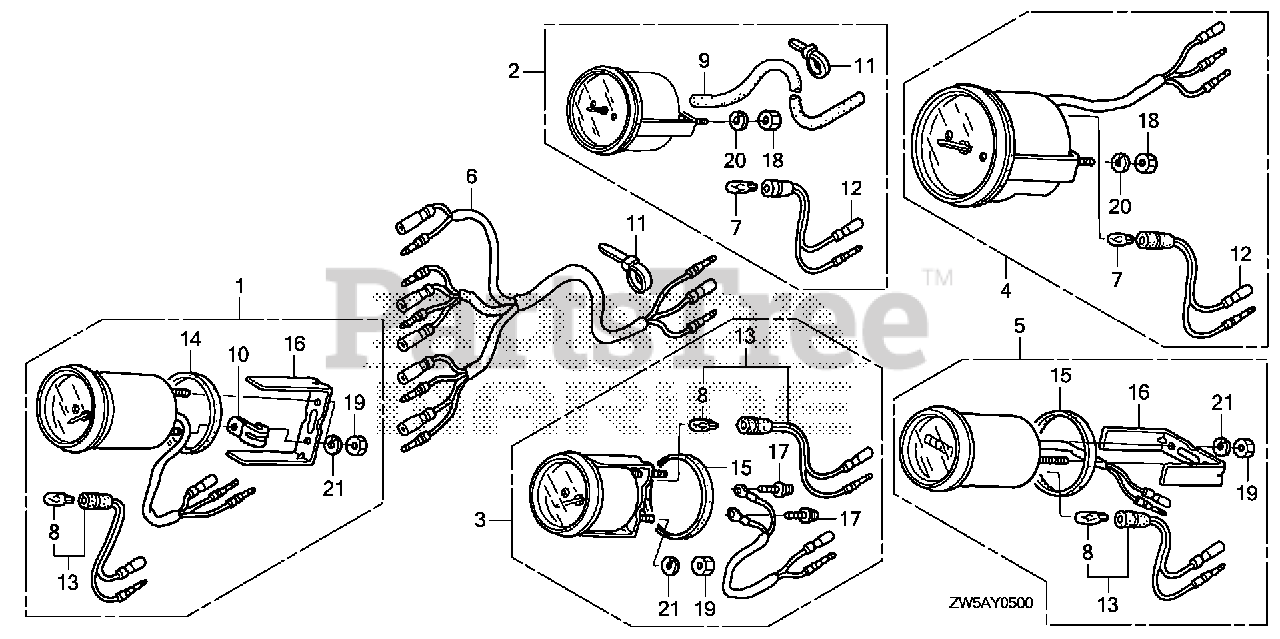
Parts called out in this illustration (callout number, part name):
1	METER KIT, TRIM (WHITE)
1	METER KIT, TRIM (B)
2	SPEEDOMETER KIT (WHITE)
2	SPEEDOMETER KIT (B)
3	METER KIT, VOLT (WHITE)
3	METER KIT, VOLT (B)
4	METER KIT, TACHO (WHITE)
4	METER KIT, TACHO (B) (BLACK)
5	METER KIT, HOUR (WHITE) (NA USE ALT:39700-ZW5-000ZA)
5	METER KIT, HOUR (B) (NA USE ALT:39700-ZW5-000ZA)
6	HARNESS ASSY., METER (B)
7	BULB, WEDGE BASE (T10) (12V 1.7W) (STANLEY)
8	BULB, WEDGE BASE (12V 1.7W)
9	TUBE, SPEED METER (4X7X8000)
10	CLAMP
11	BAND, SELF-LOCK
12	SOCKET
13	SOCKET
14	GASKET
15	GASKET
16	BRACKET
17	SCREW-WASHER (3X22)
18	NUT, HEX. (5MM)
19	NUT, HEX. (4MM)
20	WASHER, SPRING (5MM)
21	WASHER, SPRING (4MM)
